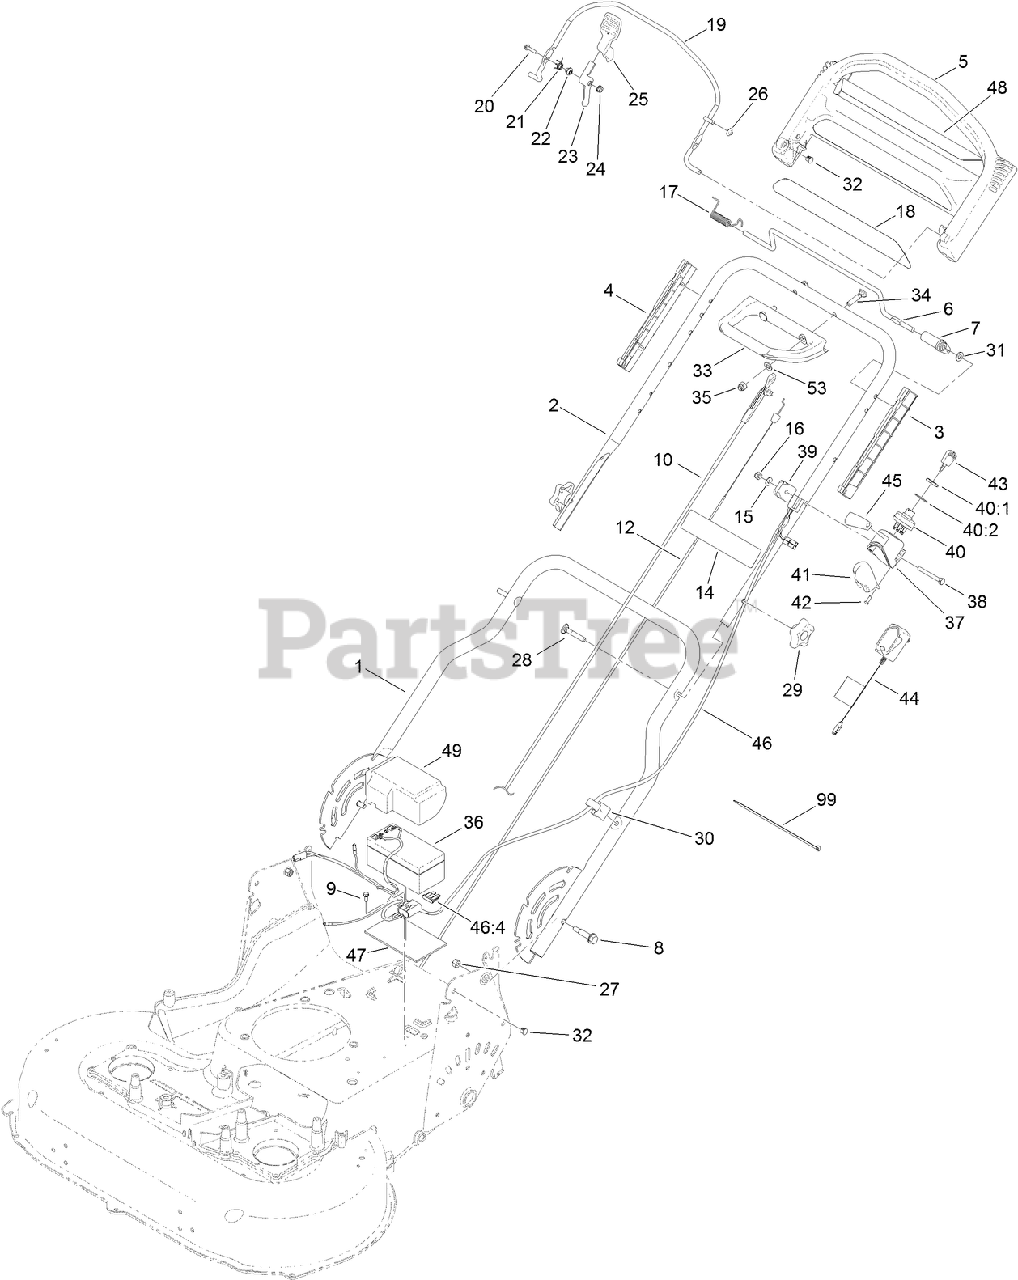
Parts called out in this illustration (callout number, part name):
1	HANDLE-LOWER
2	HANDLE-UPPER
3	GUIDE-LH
4	GUIDE-RH
5	HANDLE-CONTROL
7	LEVER-TRACTION
8	BOLT-SHOULDER, HHF
9	SCREW-TAPTITE
12	CABLE-TRACTION
14	DECAL-WARNING
15	WASHER-FLAT
16	NUT-LOCK, NI
19	BAIL-BRAKE
20	SCREW-HWH
21	SPRING-TORSION
22	SPACER
23	LEVER
24	NUT-LOCK, FLANGE
26	NUT-SPEED
27	NUT-LOCK, NI
28	SCREW-HANDLE
29	KNOB-HANDLE
30	GUIDE-CABLE
31	WASHER-PLAIN
32	PLUG-DOME
33	HANDLE-ASSIST, TRACTION
34	SCREW-HANDLE
35	NUT-HEX, NYLON CAP
36	BATTERY-WET
37	HOUSING-SWITCH, KEY
38	SCREW-HH
39	ANCHOR-CABLE, UPPER
40	SWITCH-STARTER
40:1	NUT-HH
40:2	WASHER-LOCK
41	COVER-SWTCH
42	SCREW-PPH
45	DECAL-SWITCH, IGNITION
46	HARNESS-WIRE
46:4	FUSE-40 AMP
47	FOAM-BATTERY
48	DECAL-ASSIST, TRACTION
49	COVER-BATTERY
53	SPACER
99	TIE-CABLE
